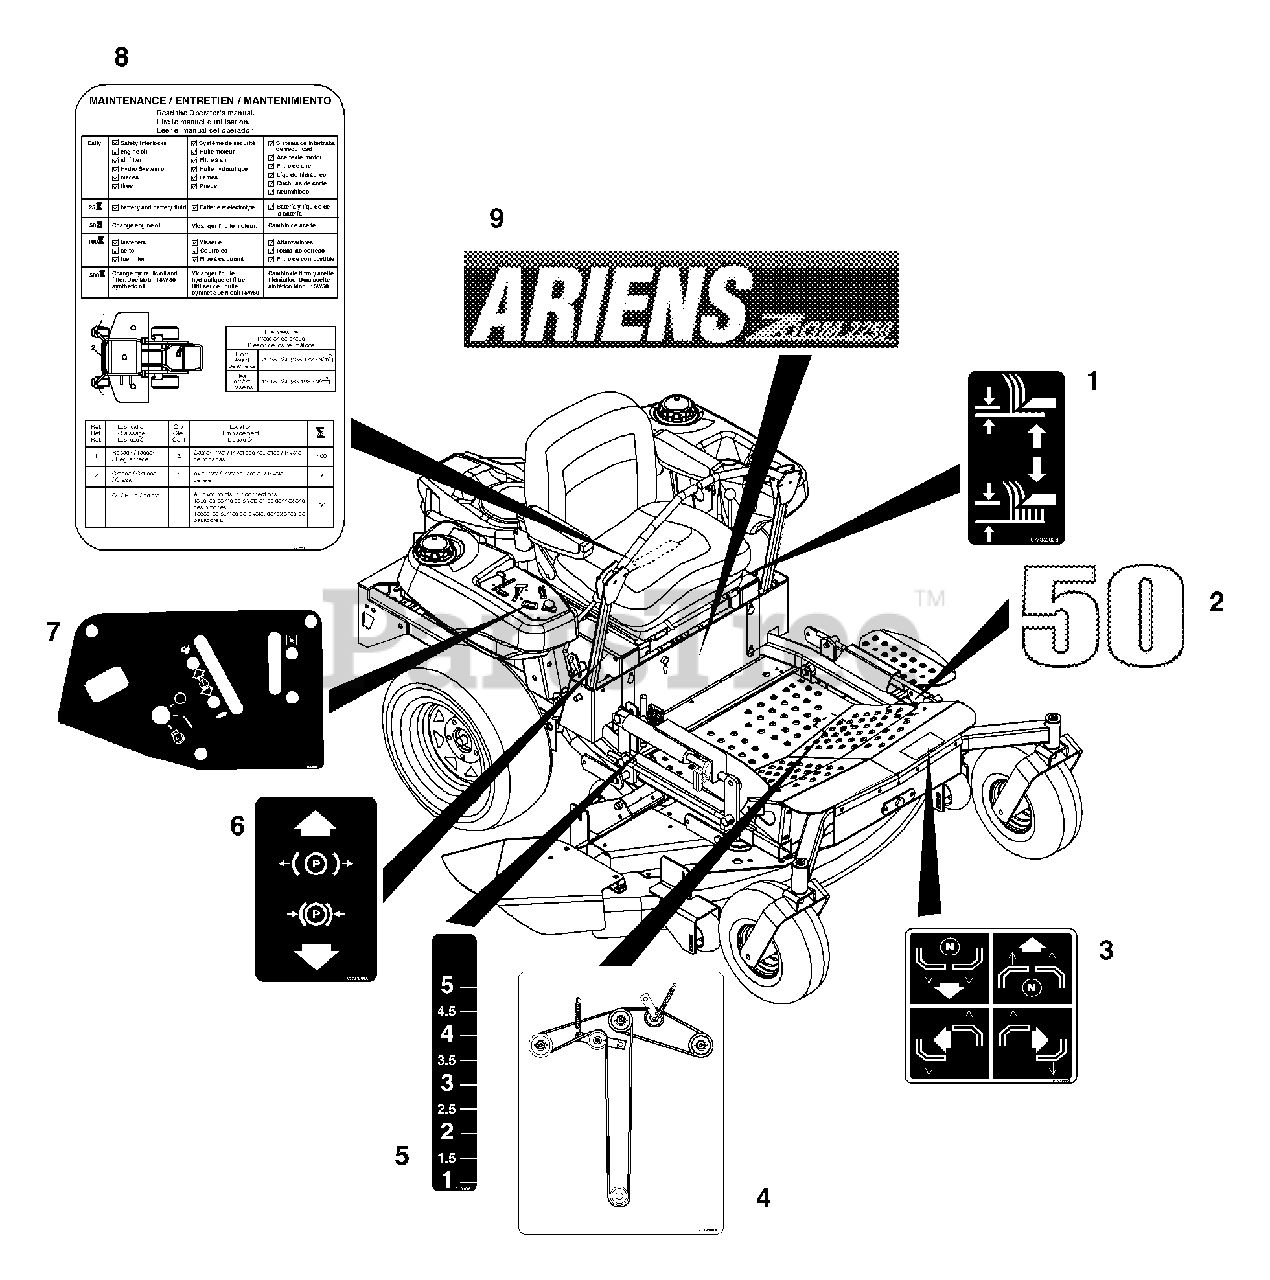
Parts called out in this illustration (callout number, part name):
1	DECAL- LIFT LEVER
2	DECAL, 50
3	DECAL, INSTRUCTIONAL-STEERING
4	DECAL, GRAVELY BELT DIAGRAM
5	DECAL, HEIGHT OF CUT
6	DECAL, PARKING BRAKE LEVER
7	DECAL, ZOOM/ZT CONTROL PANEL
8	DECAL- SERVICE INSTRUCTIONS
9	DECAL, ZOOM 2250 LOGO
